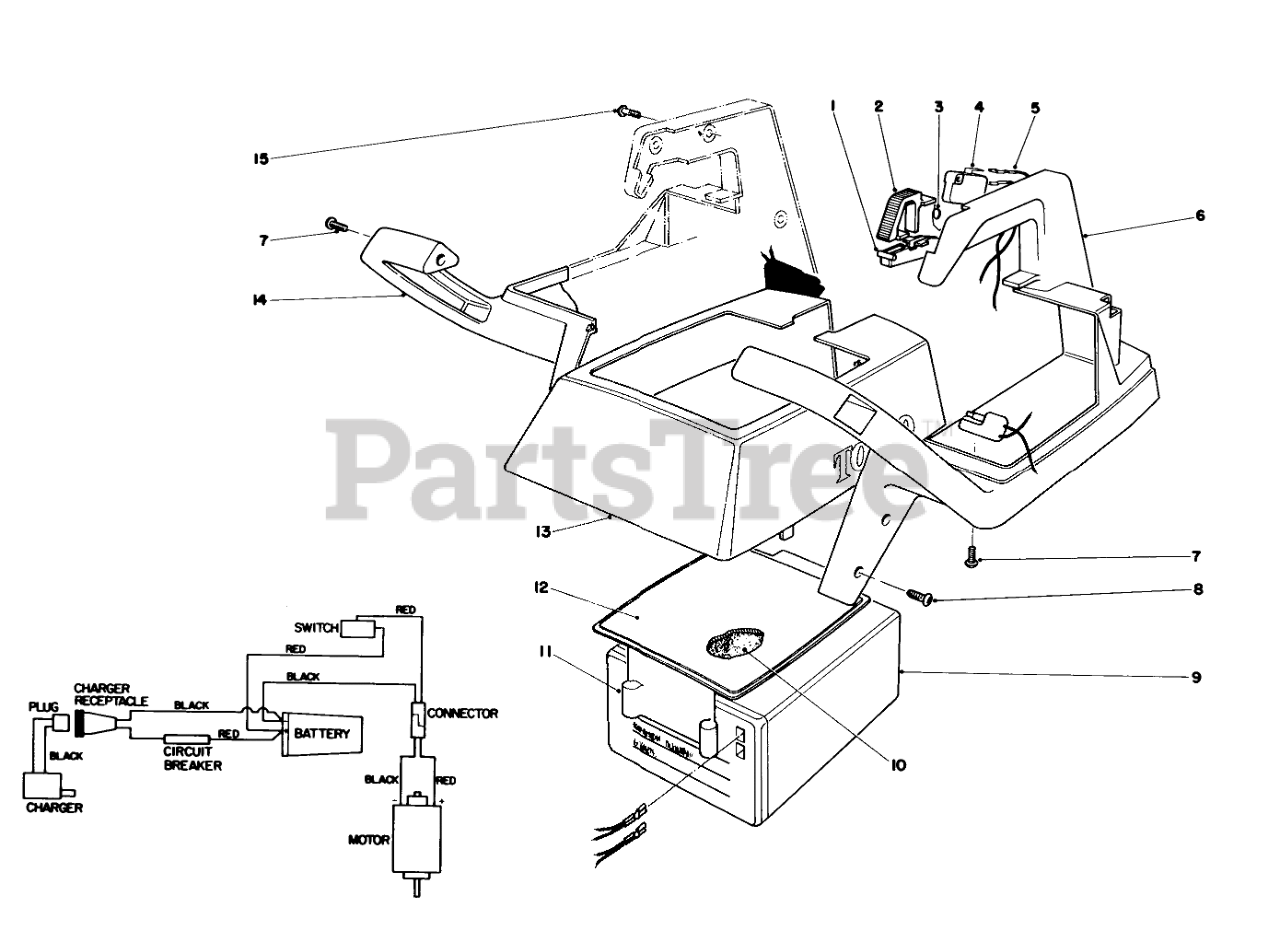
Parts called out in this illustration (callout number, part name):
1	TRIGGER
2	TRIGGER LOCK
3	SPRING
4	Switch
5	Wiring Harness
6	LH BATTERY CASE/HNDL
7	Screw
8	10-16 X .31 SCREW
9	BATTERY
10	FOAM PAD
11	CONTROL PANEL, CL-710
12	DECAL CL 710 PANEL
13	Cover
14	RH BATTERY CASE/HNDL
15	SCREW-PPH
